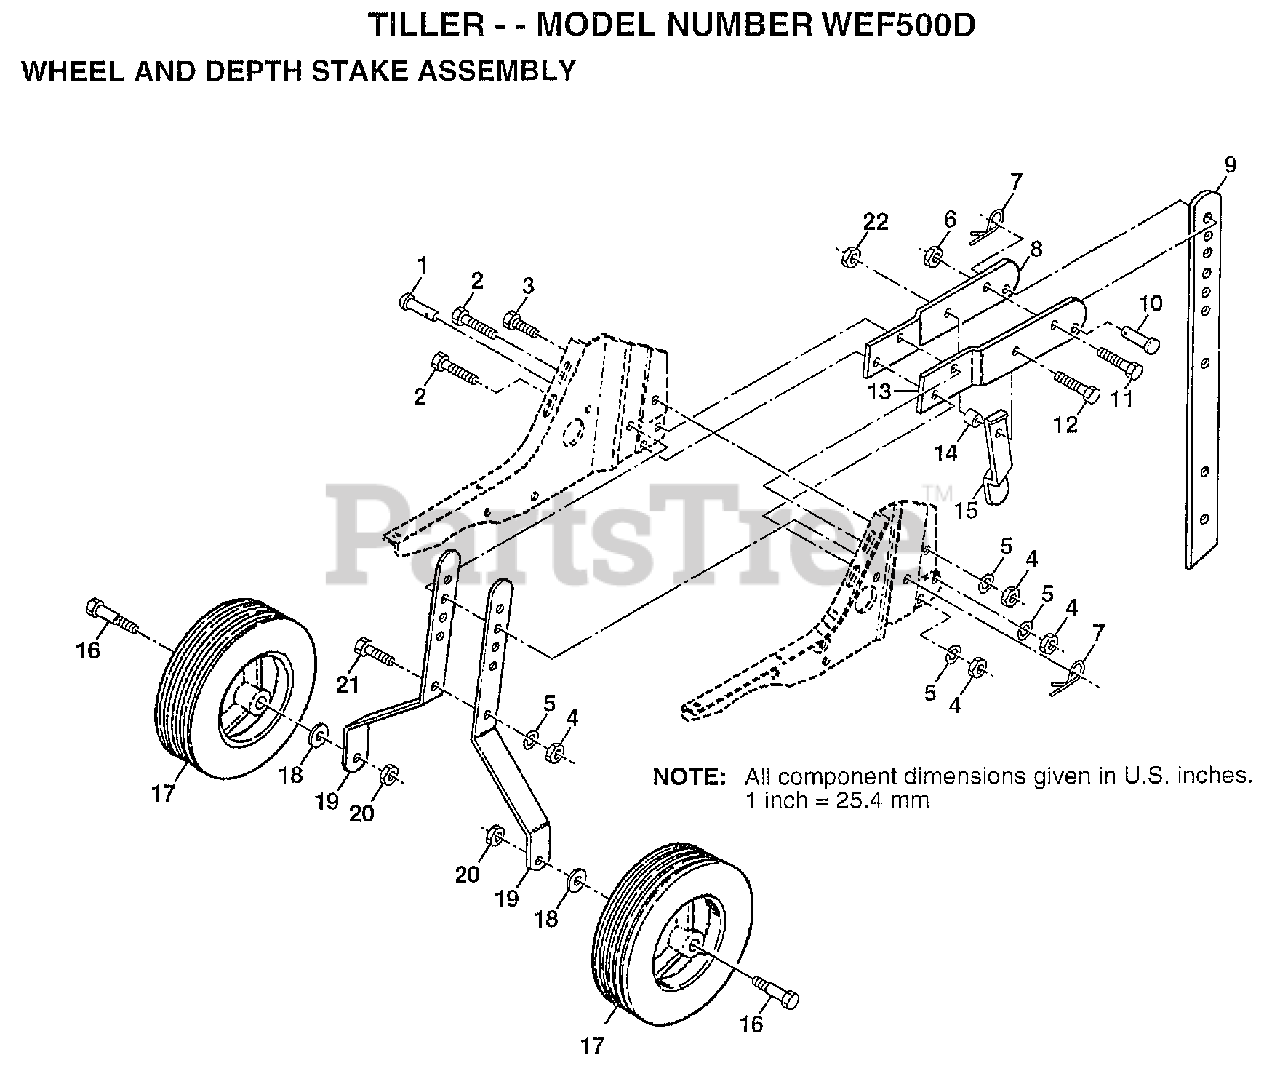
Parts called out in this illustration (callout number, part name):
2	NUT.HEX.5/16-18
3	LOCKWASHER
4	WASHER
5	SPRING.RETAINER
6	BOLT
7	STAKE.SUPT.TILLER
9	NUT
10	DRILLED RIVET RT
12	BOLT
13	STAKE SPRING CT
14	BOLT SHOULDER
15	WHEEL
16	WASHER
19	NUT
20	BOLT.HEX.5/16-1.5
